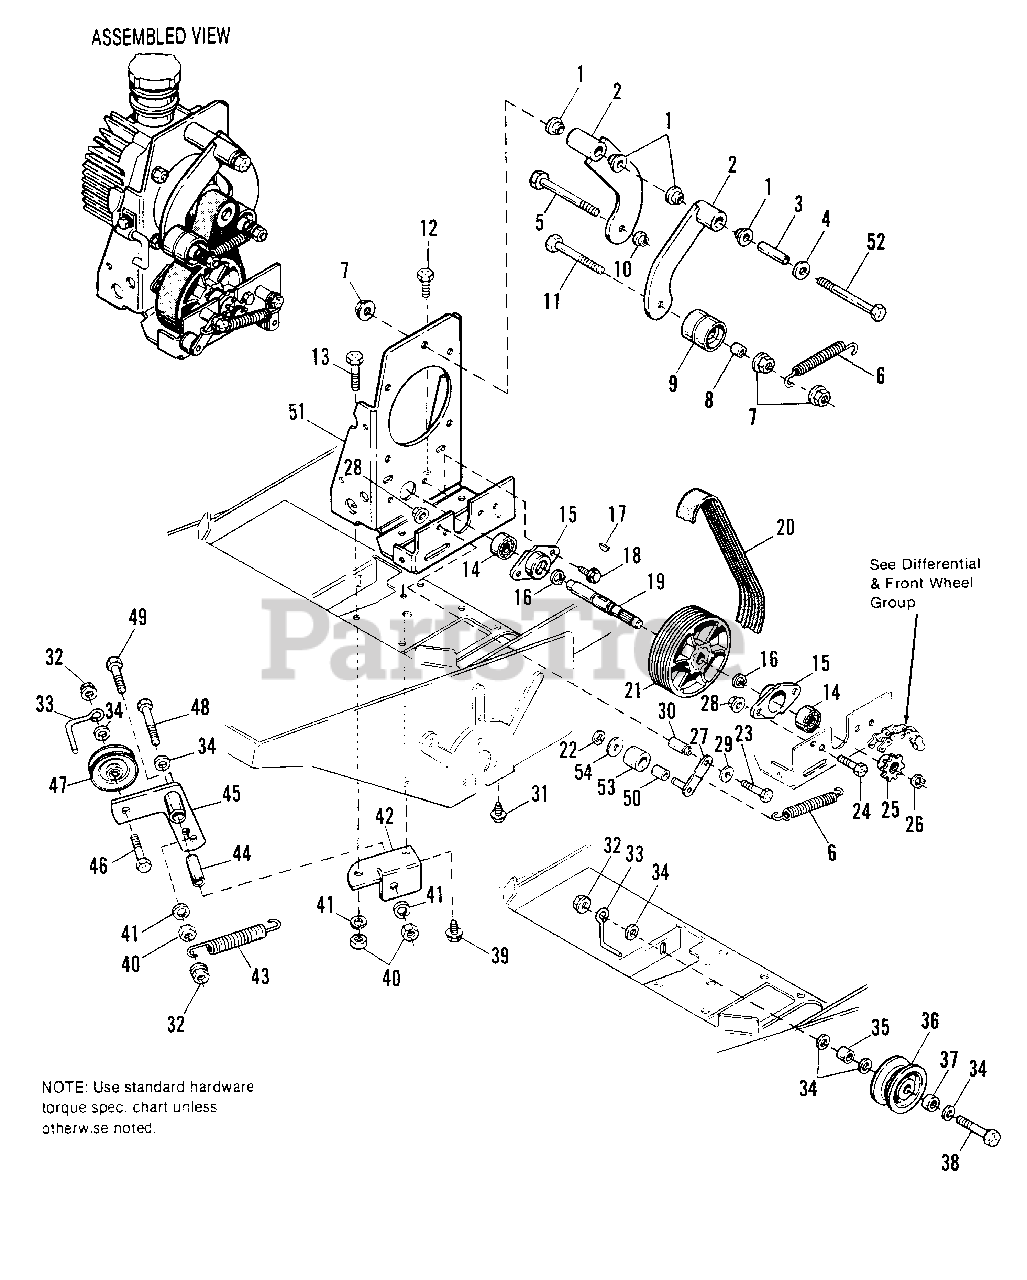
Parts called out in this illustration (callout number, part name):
2	IDLER ARM ASSY.
3	TUBE, Pivot
4	WASHER, 3/8
5	CAPSCREW, Hex, 3/8-16 x 3-1/2
6	SPRING, Tension, Idler Assy.
7	NUT, Hex Flangelock, 3/8-16
9	PULLEY, Idler
11	CAPSCREW, Hex, 3/8-16 x 3
12	CAPSCREW, Hex, 3/8-16 x 3/4
13	CAPSCREW, Hex, 3/8-16 x 1
14	BEARING, Ball
15	RETAINER, Bearing
16	RING, Retaining
17	KEY, Woodruff
18	SCREW, Taptite, 5/16-18 x 3/8
20	BELT, Drive, Poly "V"
21	PULLEY, DRIVE
22	'E" RING, Retaining
23	CAPSCREW, Hex Head 5/16-18 x 2 G5
24	CAPSCREW, Hex, 5/16-18 x 5/8
25	SPROCKET, Drive (9 Teeth)
26	RING, Retaining
27	CONTROL ARM ASSY.
28	NUT, Hex Flange Lock, 5/16-18
29	WASHER, Plain
30	SPACER, Control Arm Assy.
31	SCREW, Taptite, 5/16-18 x 1/2
32	NUT, Flange Lock, 3/8-16
34	WASHER, 3/8
36	PULLEY, Idler
38	CAPSCREW, Hex Hd., 3/8-16 x 2
39	SCREW, Hex Taptite, 5/16-18 x 1/2
40	NUT, Hex, 3/8-16
41	LOCKWASHER, 3/8
42	BRACKET, Clutch Arm
45	CLUTCH ARM ASSY.
46	CAPSCREW, Hex, 3/8-16 x 1-3/4
47	PULLEY, Idler
48	CAPSCREW, Hex Hd., 3/8-16 x 2-1/4
49	CAPSCREW, Hex, 3/8-16 x 1-1/4
50	SPACER, Roller
51	BRACKET, Pump Mount
52	CAPSCREW, Hex, 3/8-16 x 4
53	ROLLER, Chain
54	WASHER, Plain, 3/8 x 1-1/4
